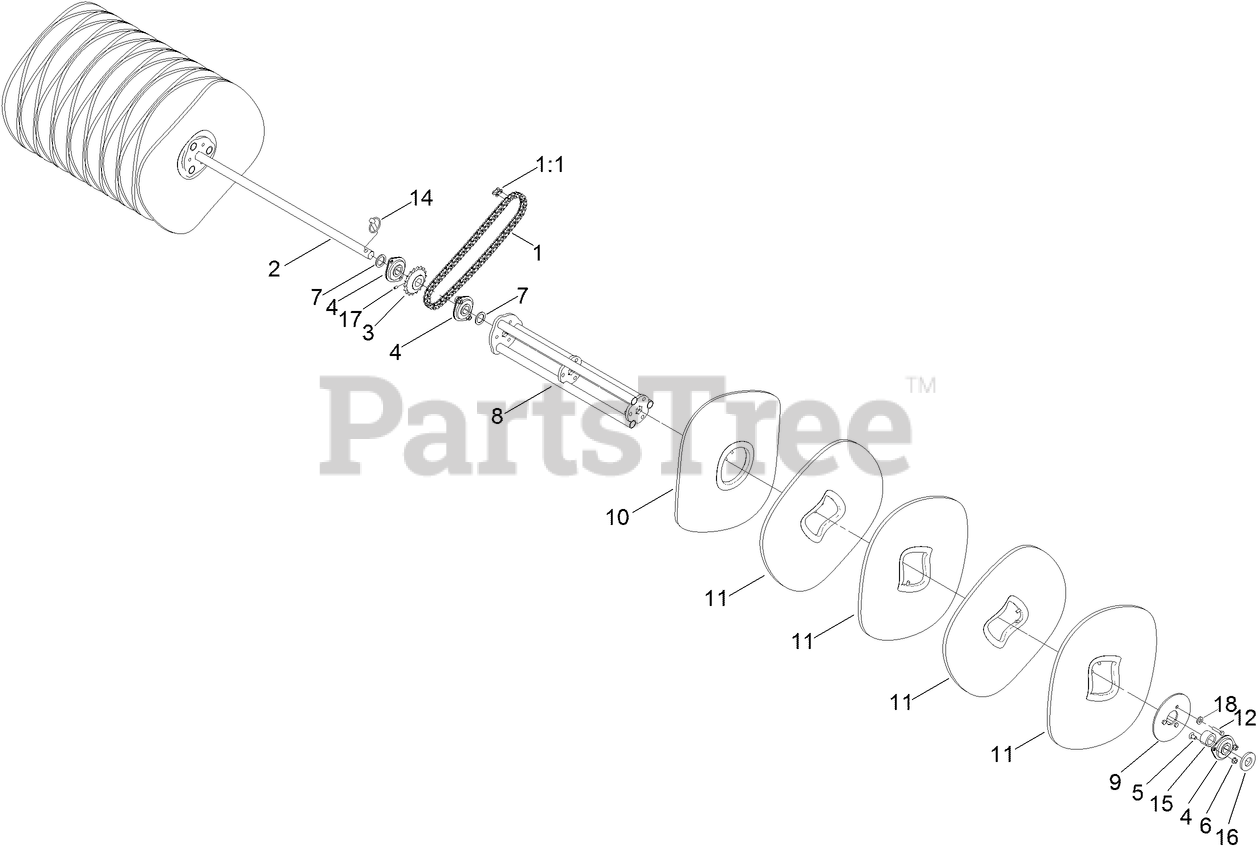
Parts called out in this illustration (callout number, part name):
1	CHAIN-ROLLER
1:1	LINK-CONNECTING, NO. 50
2	HEX SHAFT
3	SPROCKET-CHAIN
4	BEARING-HEX
5	SCREW-CARR
6	NUT-HF
7	WASHER-THRUST
8	BRISTLE-CARRIER
9	PLATE-BRISTLE, CARRIER
10	BRISTLE-CONE, HYBRID
11	WAFER-BROOM
12	Screw-HH
14	PIN-LYNCH
15	SPACER-CASTOR
16	WASHER
17	SCREW-SET, HSH
18	WASHER-PLAIN
